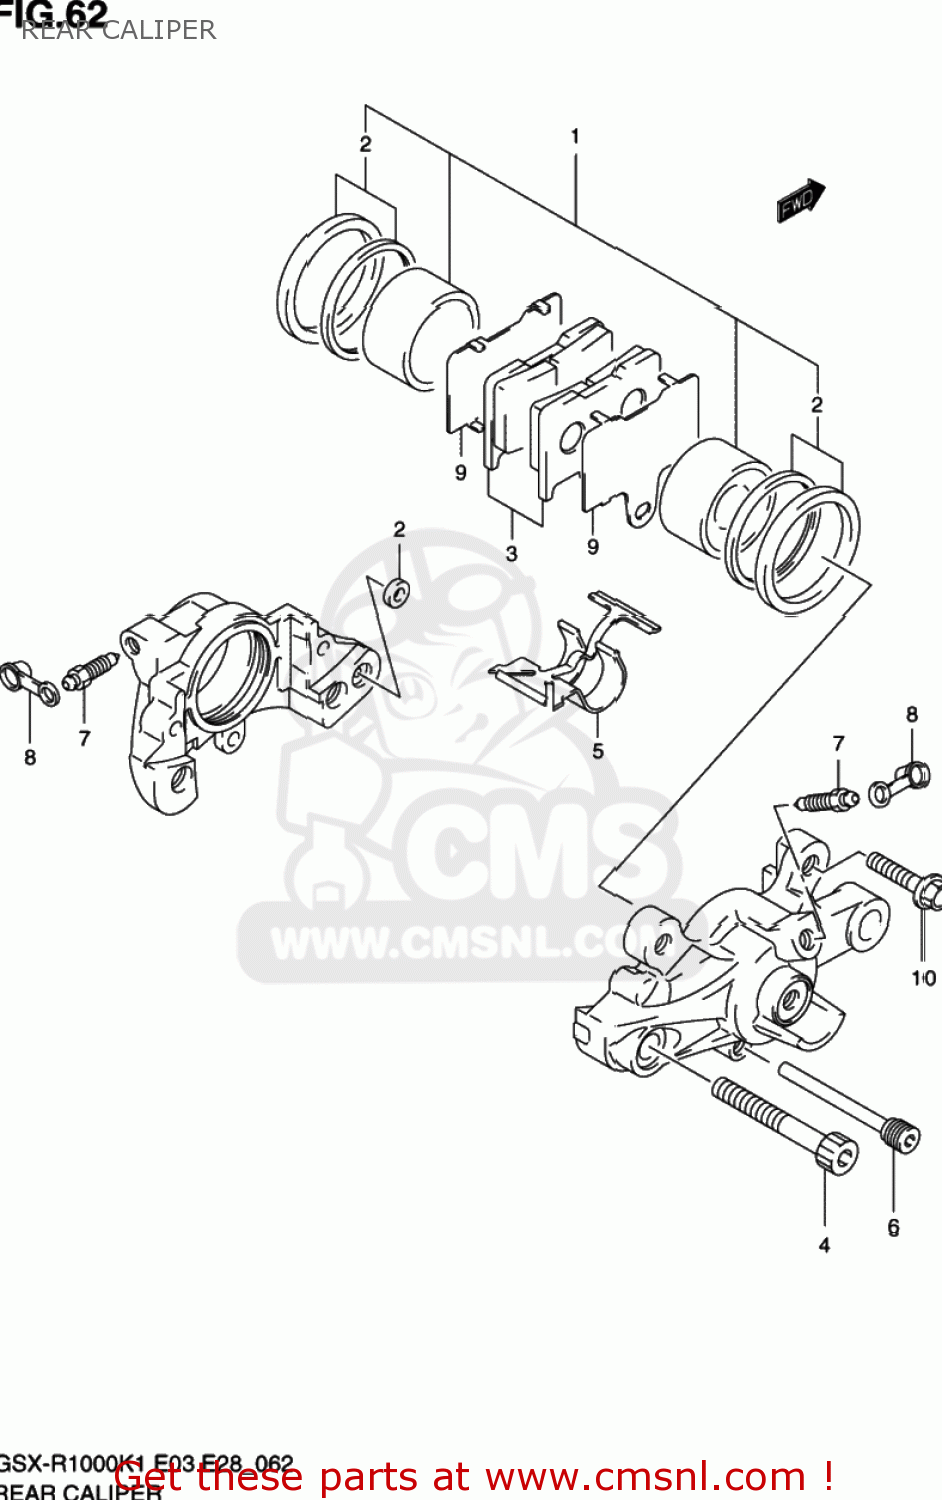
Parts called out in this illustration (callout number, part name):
1	PISTON SET
2	SEAL SET,PISTON
3	PAD SET (NAS)
4	BOLT,HOUSING
5	SPRING
6	PIN,PAD
7	BLEEDER
8	CAP,BLEEDER
9	SHIM,PAD
10	BOLT(8X28)
